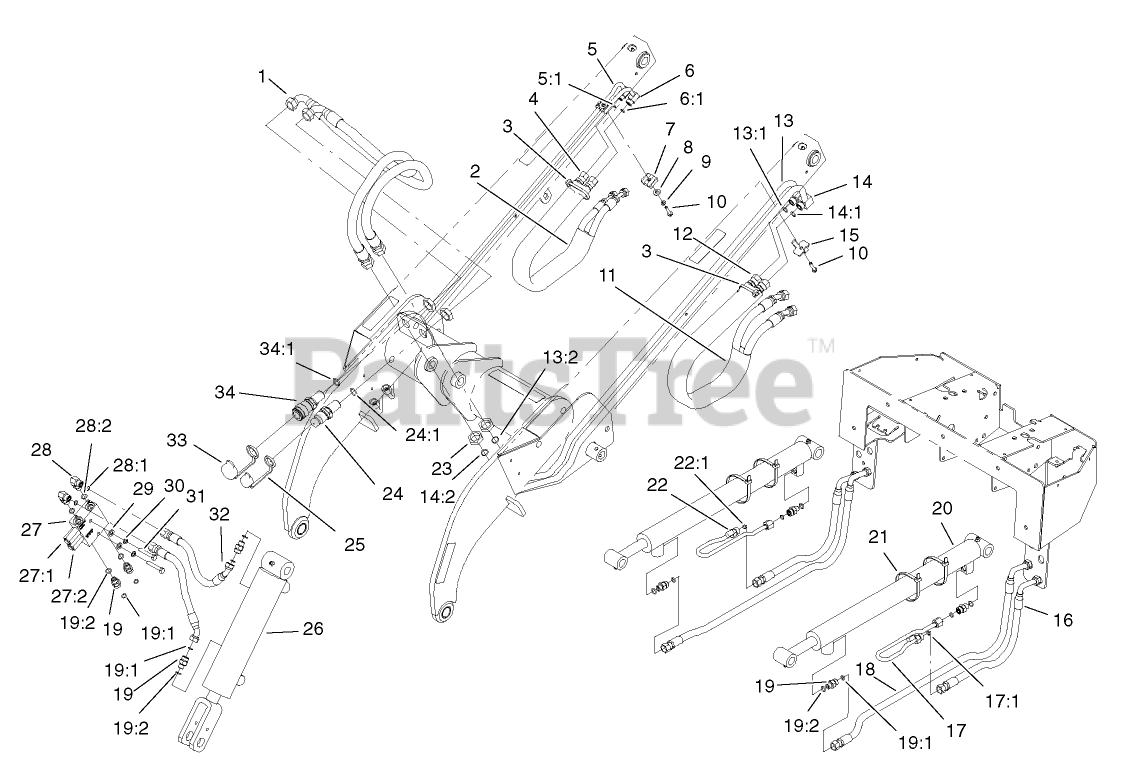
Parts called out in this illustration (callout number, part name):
1	HOSE ASM
2	SLEEVE-PROTECTIVE
3	TIE-CABLE
4	HOSE-HYD
5	HYD TUBE ASM
5:1	O-RING
6	HYD TUBE ASM
6:1	O-RING
7	CLAMP-TUBE
8	WASHER-FLAT
9	WASHER-LOCK
10	SCREW-HWH
11	SLEEVE-PROTECTIVE
12	HOSE-HYD
13	HYD TUBE ASM
13:1	O-RING
13:2	O-RING
14	HYD TUBE ASM
14:1	O-RING
14:2	O-RING
15	PLATE-CLAMP, TUBE
16	HOSE-HYD
17	HYD TUBE ASM
17:1	O-RING
18	HYD HOSE ASM
19	FITTING-STRAIGHT
19:1	O-RING
19:2	O-RING
20	CYLINDER-LIFT
21	TIE-CABLE
22	HYD TUBE ASM
22:1	O-RING
23	NUT-LOCK, BULKHEAD
24	BULKHEAD NIPPLE ASM
24:1	O-RING
25	CAP-DUST, NIPPLE
26	CYLINDER-TILT
27	VALVE-RELIEF, CROSSOVER
27:2	CARTRIDGE-RELIEF
27:3	CARTRIDGE-RELIEF
28	FITTING-ELBOW, 90 DEG
28:1	O-RING
28:2	O-RING
29	WASHER-PLAIN
30	WASHER-LOCK
31	SCREW-HH
32	HOSE-HYD
33	CAP-DUST, COUPLER
34	BULKHEAD COUPLER ASM
34:1	O-RING
